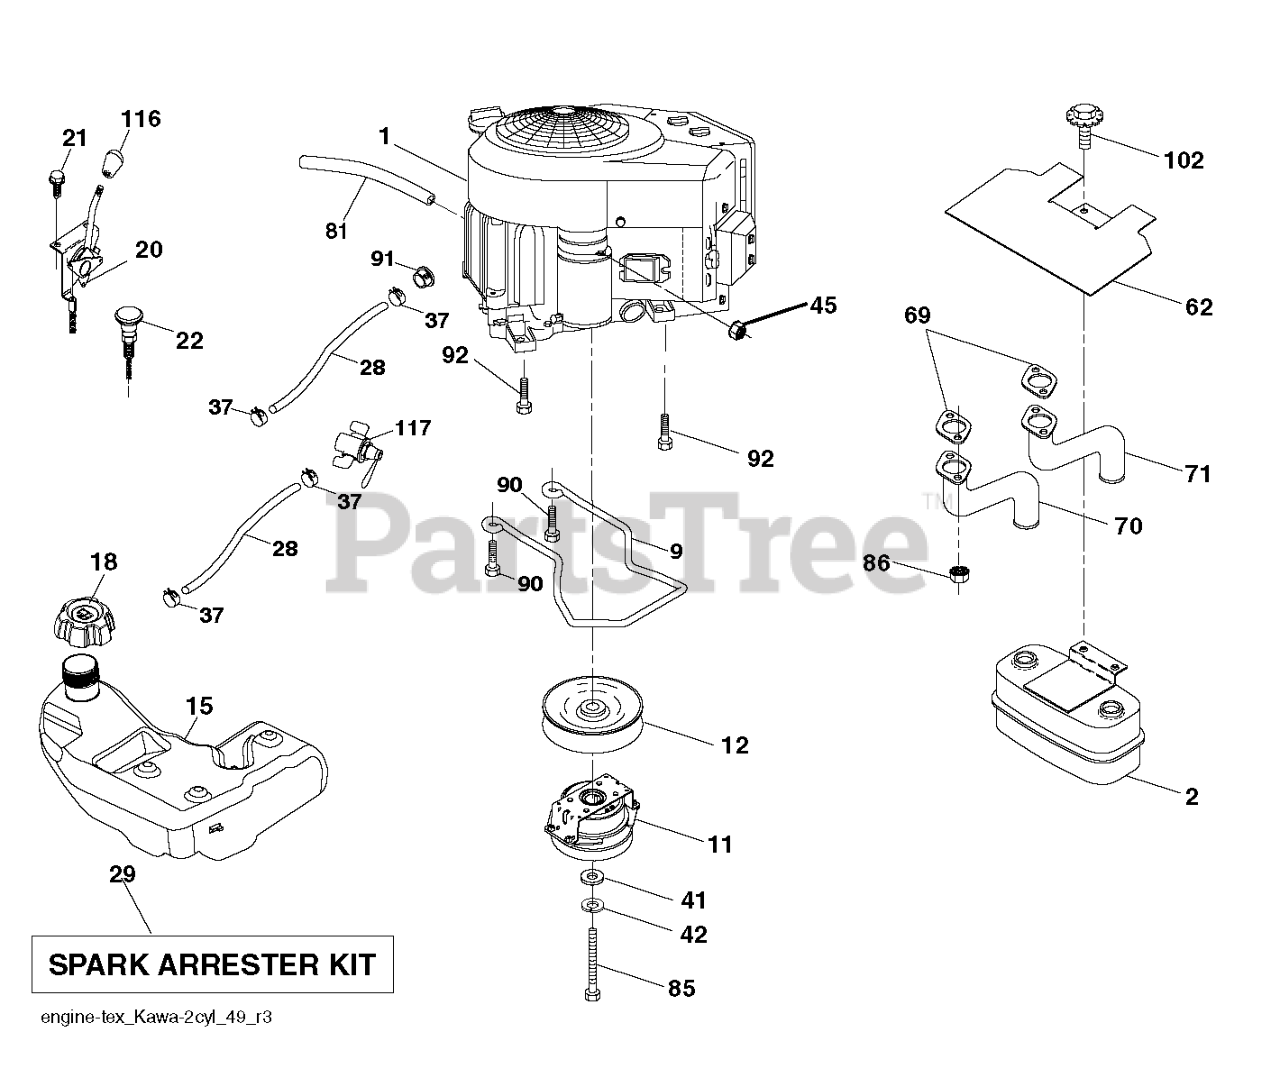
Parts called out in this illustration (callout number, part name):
2	MUFFLER.ASM.TWN.EXTNDED.DFLCTR
9	KEEPER.BELT.ENG.4.25"2.BLT.431
11	CLUTCH.OGURA.5.0PD.GT1.5A-EH01
12	PULLEY ENGINE
15	TANK.ASM.FUEL.4R.GAL.EPA.17
18	CAP ASSY FUEL 3" BLACK
20	CONTROL.THROTTLE.PRO.
21	SCREW.#10X.750
22	CONTROL.CHOKE.ERGO.PUSH-IN.BLA
28	LINE.FUEL.1/4" ROLL
29	KIT.SPARK ARRESTOR 794945 B&S
37	HOSE CLAMP
42	WASHER 7/16 LOCK
45	NUT
62	SHIELD.HEAT.MUFFLER
70	TUBE.EXHAUST.LH.FR961/FR730
71	TUBE.EXHAUST.RH.FR961/FR730
81	TUBE, DRAIN OIL ASM.
85	BOLT.HEX.7/16-20X3.GR5.YELLOW
86	NUT.HEX.FLANGE.TOPLOCK
90	SCREW 3/8-16X1
91	BUSHING.1.375OD
92	SCREW 3/8-16X1
102	SCREW
116	KNOB - SHIFT
117	VALVE FUEL RESERVE
